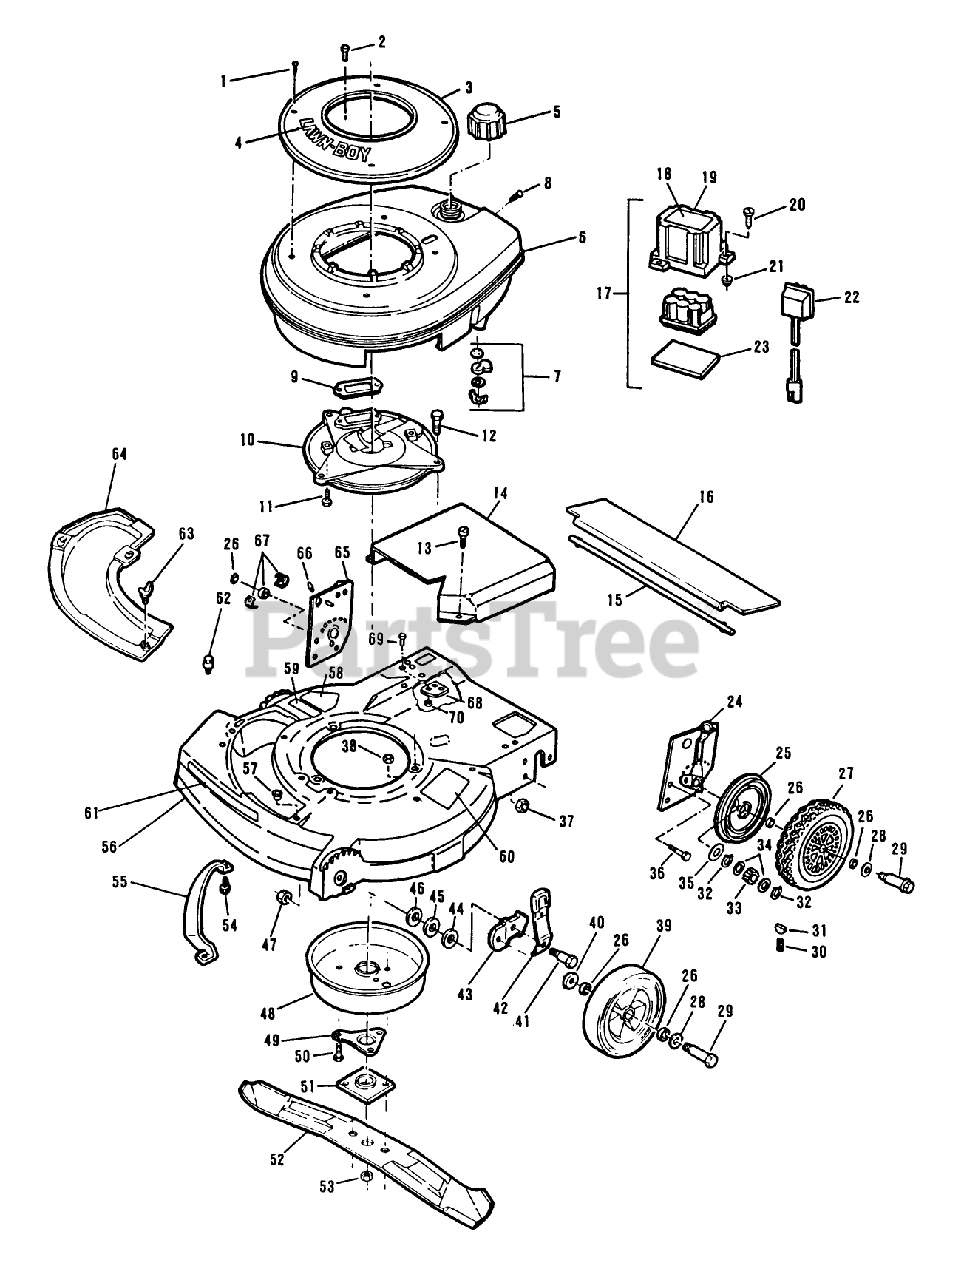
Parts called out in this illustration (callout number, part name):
1	SCREW - SELF TAPPING
2	SCREW SEMS SM
5	FUEL CAP & INSERT
7	SHUT OFF VALVE KIT
8	SCREW S
11	SCREW V
12	SCREW-HH
13	SCREW SEMS TRM HEX HD
20	SCREW - SELF TAPPING
21	NUT-CLIP
23	PAD-BATTERY
26	WASHER
28	SPACER
29	BOLT WHEEL
30	SPRING
31	KEY
32	RET RING
33	PINION BROCKWAY
34	SPACER/GR ALGHNY
37	NUT-LOCK F
38	NUT-LOCK F
40	WASHER WROUGHT
41	BOLT
42	SPRING ARM ASM
44	WASHER
45	WASHER
46	WASHER
47	LOCKNUT
48	MUFFLER COVER F
49	SUPPORT F
50	SCREW
51	PLATE AND COLLAR ASM
53	NUT-BLADE
55	BAR-TOE
60	PAD FOOT
63	WING SCREW LAWRE
66	**FITTING LINCOLN
67	REAR AXLE BEARING
68	BOLSTER
70	LOCKNUT E
